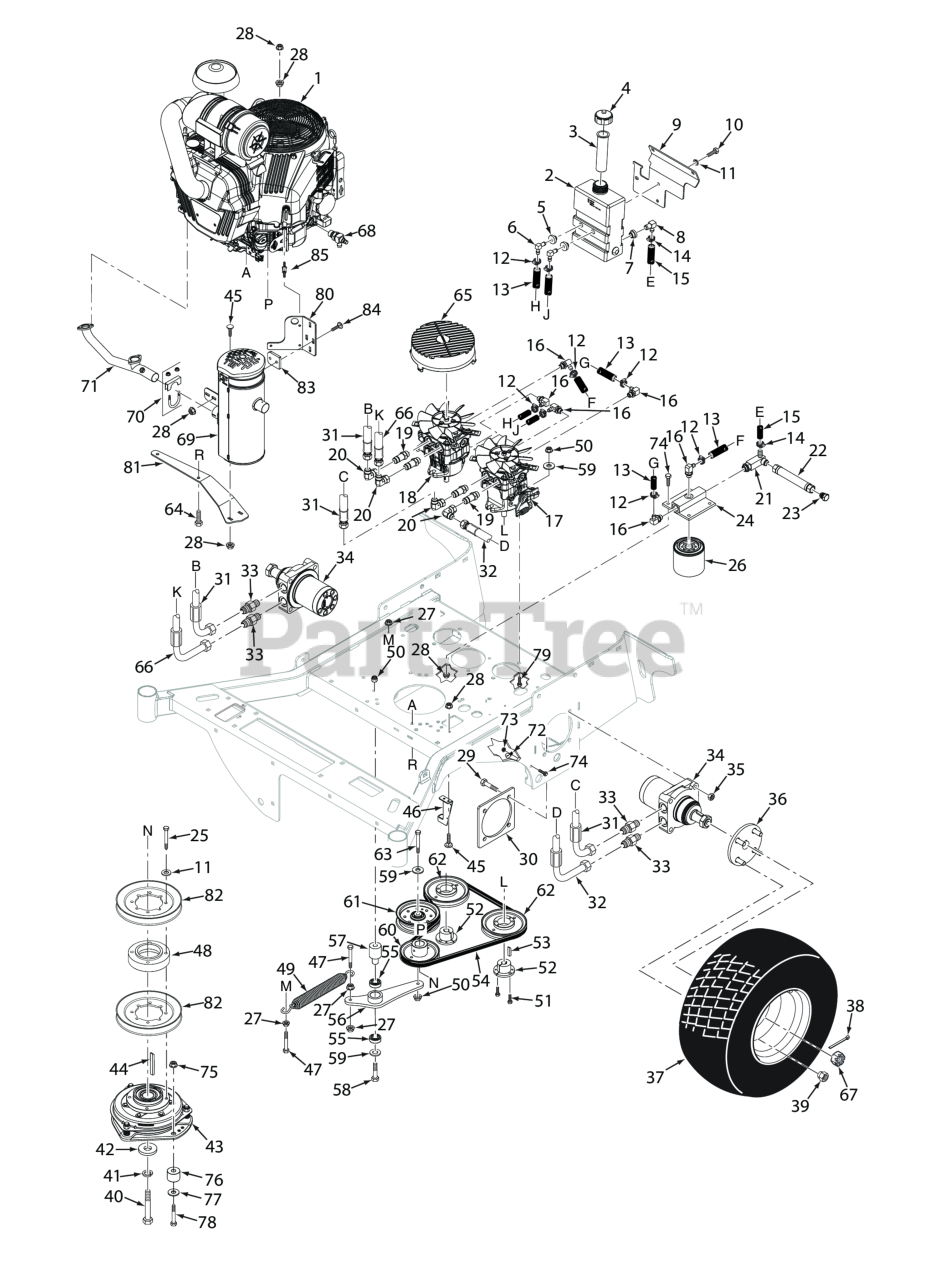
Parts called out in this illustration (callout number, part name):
1	Engine, Briggs & Stratton 37 BV-EFI (61E8770002J1)
2	Hydro Tank Assy., SVRII
3	Insert, Filler Neck
4	CAP, HYDRAULIC TANK
5	Bushing, 0.56" Dia. Viton
6	Elbow, 90 Degree, 9/16-18 JIC x 9/16 O-Ring
7	Bushing, 0.78" Dia. Viton
8	Fitting, 90 Degree - 1/2" Hose
9	Bracket, Hydro Tank Mounting
10	BOLT, SERRATED FLANGE HEX HEAD 5/16-18 X 3/4"
11	Lockwasher, 5/16 (.317 x .586 x .078) Helical Spring
12	Clamp, .69" Max. / .25" Min. Dia.
13	Hose, 3/8" ID - 10-1/4" Long (Order By The Inch)
14	Clamp, Cable 3/4" I.D.
15	Hose Assembly, 1/2" ID (Oil Reservoir to Filter Base)
16	Elbow, 90 Degree - 9/16" O-Ring x 3/8" Hose
17	Pump, LH - SVRII
18	Pump, RH - SVRII
19	Union, O-Ring to JIC
20	Elbow, 1/2 JIC Female to 1/2 JIC Male
21	Tee, 3/4" O-Ring
22	Drain, Hose Assembly
23	Plug, JIC 3/4-16 UNF
24	Filter Head Assembly
25	Bolt, M8-1¼ x ½"
26	OIL FILTER, SPECIAL
27	NUT, 3/8-16 SERRATED FLANGE HEX HEAD
28	Nut, Serrated Flange 5/16-18 (Right Front Engine Mounting, Briggs and Kohler Only)
29	Bolt, Hex Hd. 1/2-13 x 2-1/2" (lower)
30	Plate Weldment, Motor Backing
31	Hose Assy., 27-1/2"
32	Hose Assy., 15-1/4"
33	TUBE UNION, 3/4-16 JIC TO 7/8-14 "O" RING
34	Wheel Motor, SVRII
35	Locknut, Hex 1/2-13 Center Lock
36	Wheel Hub Assy., SVRII
36	Bolt, Serr. Flange 1/2-20 x 4.563"
37	Wheel Assembly, 24 x 12-12 (SPZ61)
37	Tire, 24 x 12-12 (SPZ61)
37	(52") Rim 481851 (61") Rim w/Stem
38	Pin, Cotter 9/16" x 1-1/2"
39	Wheel Nut, 1/2-20 x 13/16
40	Bolt, Hex Head 7/16-20 x 3" w/t Patch
41	Lockwasher, 7/16� Spring
42	Flatwasher, 7/16-.469 x 1.75 x .25 (48, 52)
43	Clutch, GT3.5 (28.6mm Bore)
44	Key, 1/4 x 1/4 x 3-1/2"
45	Bolt, 5/16-18 x .75 RHSN Carriage
46	Bracket, Anti-Rotation
47	Bolt, Hex Head 3/8-16 x 1-1/2" Grade 8 Black
48	Hub, Clutch Pulley
49	Spring, Transmission Drive
50	HEX NUT, ELASTIC STOP LOCK, 3/8-16
51	Bolt, Hex Head 1/4-20 x 1" Grade 8 Black
52	Hub, Tapered, 15mm Bore
53	KEY, 5 MM X 5 MM X 25 MM
54	Belt, Pump Drive (37BV-EFI)
55	BEARINGS, BALL, NEUTRAL RETURN
56	Idler Arm Assy.
57	Pivot, Idler
58	Capscrew, Hex Head 3/8-16 x 3.25"
59	Flatwasher, 3/8 (.391 x .938 x .105 HD) Grade 8
60	Pulley, 4.75" DIA 1.125 DIA Bore
61	Pulley, Idler 4-1/2"
62	Pulley, 5.45 OD - Tapered Bore"
63	Bolt, Hex Head 3/8-16 x 2-1/4" - 61"
64	Bolt, Hex Head 3/8-16 x 1-3/4" (Kohler EFI)
65	Fan Cover, Pump
66	Hose Assy., 30"
67	Nut, Hex Castle 1.0-20 UNEF
68	Oil Drain, 35BV & 37BV-EFI - Briggs & Stratton
69	Muffler, 37BV-EFI
70	Clamp, Muffler (Clamp Only)
71	Manifold, 37 BV-EFI
71	O2 Sensor
72	Clamp, Cable 3/4" ID.
73	Nut, Flange Head Elastic Stop 5/16-18
74	Bolt, Heax Head 5/16-18 x 1" (48V / 52V)
75	HEX NUT, ELASTIC STOP LOCK, 5/16-18
76	Bushing, UHMW
77	Flatwasher, 5/16-.375 x .875 x .083 (35BV & 37BV-EFI)
78	Bolt, Hex Head 5/16-18 x 1-1/2" (Right Front Engine Mounting, Briggs and Kohler Only)
79	Bolt, Hex Head, 3/8-16 x 1-1/2"
80	Muffler Bracket, Valve Cover
81	Muffler Bracket, Engine
82	Pulley, Clutch 7.30 DIA
83	Strap Spacer, Muffler
84	Bolt, Carriage 5/16-18 x 1-1/4"
85	Stud, Valve Cover Exhaust Mount
